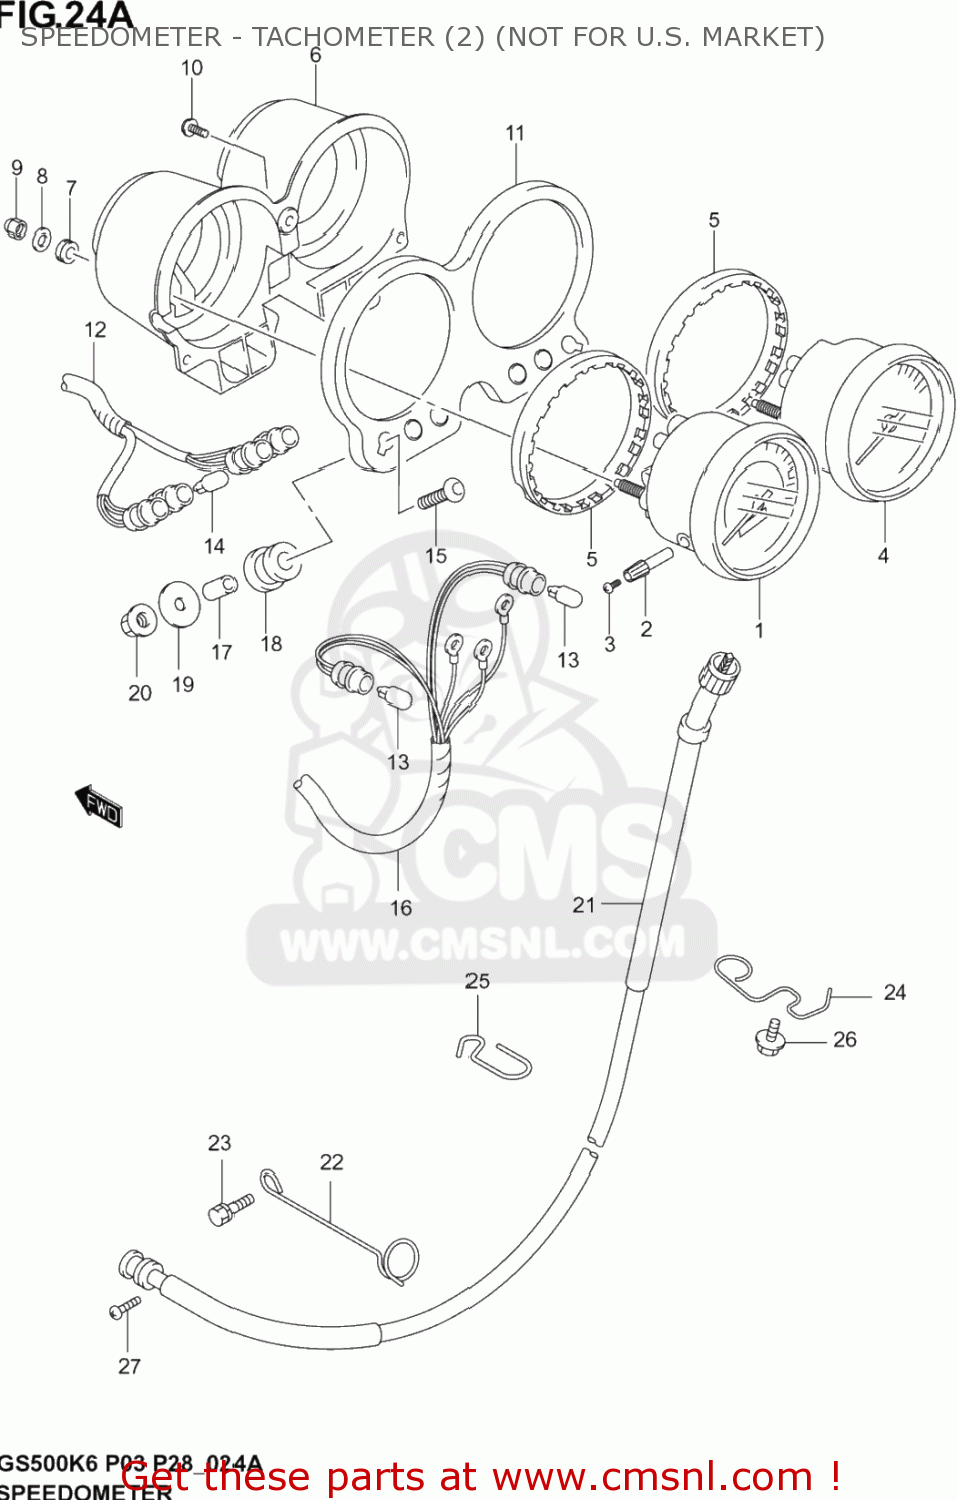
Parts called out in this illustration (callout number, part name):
1	SPEEDOMETER
2	KNOB
3	ROTOR,SPEED
4	TACHOMETER
5	DAMPER
6	COVER
7	CUSHION
8	WASHER
9	NUT
10	SCREW
11	BRACKET METER
12	SOCK.&CORD,PIL
13	BULB(12V1.7W,T10)
14	BULB (12V, 1.7W, T6.5)
15	BOLT(6X30)
16	SOCKET&CORD
17	SPACER(6.4X9X17)
18	CUSHION,METER BRACKET
19	WASHER(6.5X28X1.6)
20	NUT
21	CABLE ASSY,SPEEDOMETER
22	CLAMP,SPEEDOMETER CABLE
23	BOLT OIL LEVEL
24	GUIDE,SPEEDOMETER CABLE NO.2
25	GUIDE,SPEEDOMETER CABLE NO.3
26	BOLT OIL LEVEL
27	SCREW
